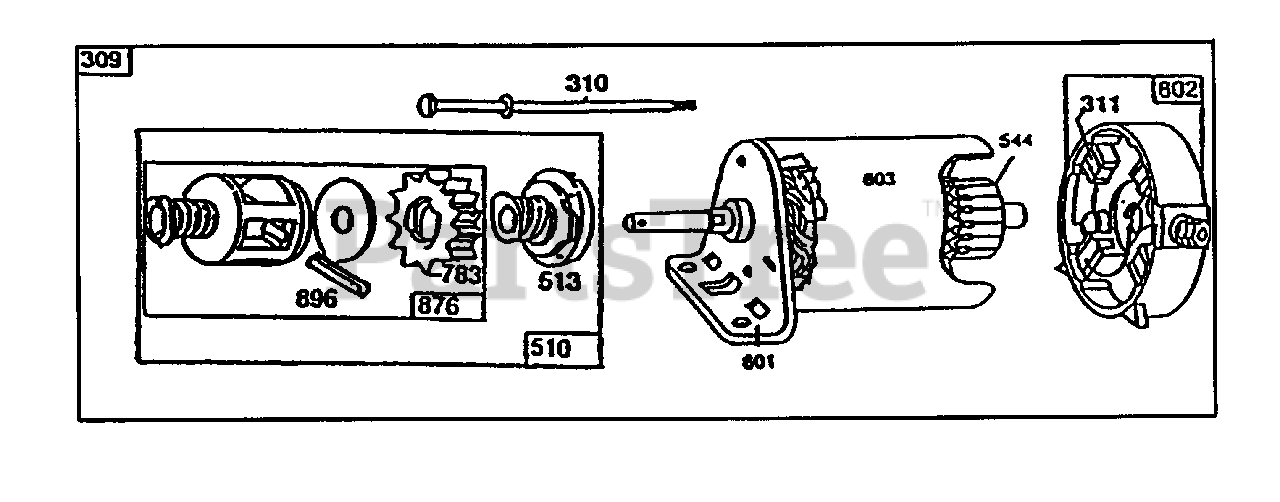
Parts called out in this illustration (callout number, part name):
309	Assembly-Motor & Drive
310	Assembly-Thru Bolt
311	Assembly-Brush
510	Assembly-Drive (Incl. Ref. #513, 783, 876 & 896)
513	Assembly-Clutch
544	Assembly-Armature
801	Assembly-End Cap
802	Assembly-Commutator, End Cap
803	Assembly-Housing (3-21/32" Long)
876	Kit-Retainer
896	Pin-Roll
